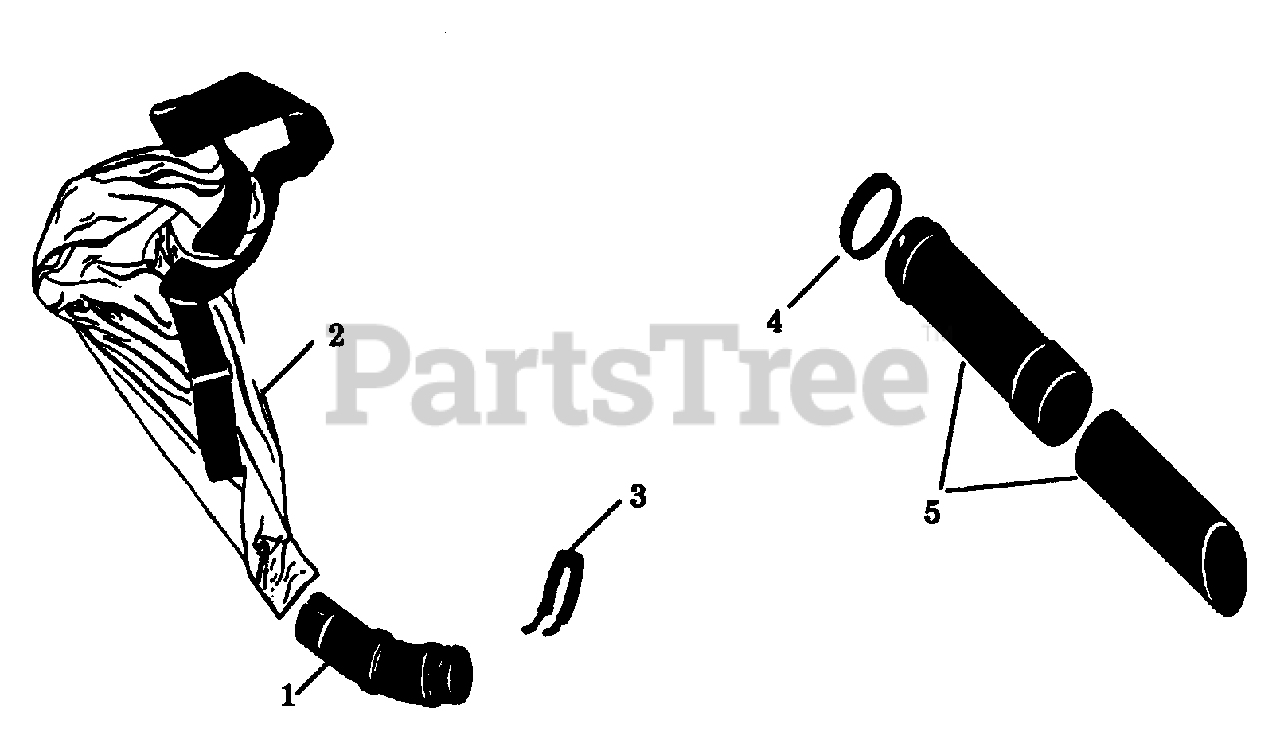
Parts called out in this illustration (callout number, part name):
2	Vacuum Bag Kit
3	Rear Handle Ass'y.
4	Spacer
5	Vacuum Tube Kit
